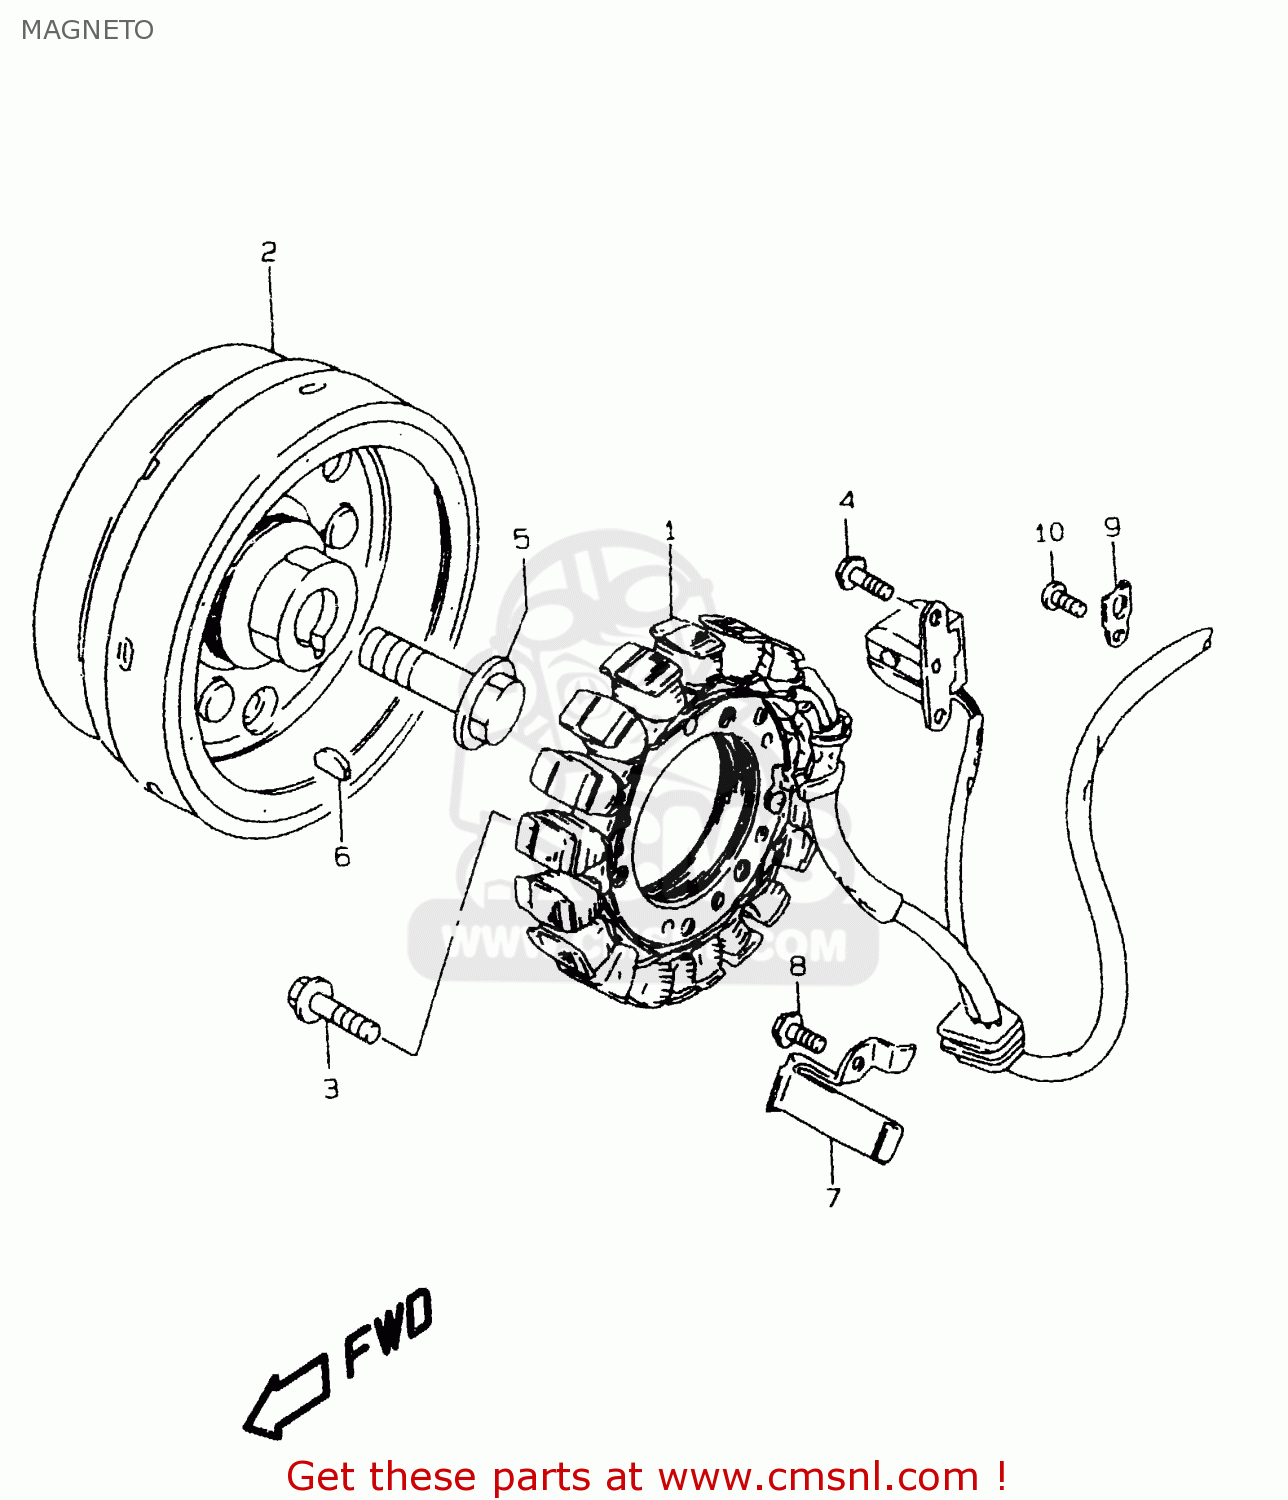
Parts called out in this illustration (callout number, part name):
1	STATOR ASSEMBLY
2	ROTOR ASSY
3	SCREW
4	BOLT
5	BOLT(14X43)
6	KEY
7	CLAMP,MAGNETO LEAD WIRE NO.1
8	BOLT
9	CLAMP,GENERATOR LEAD WIRE
10	SCREW
